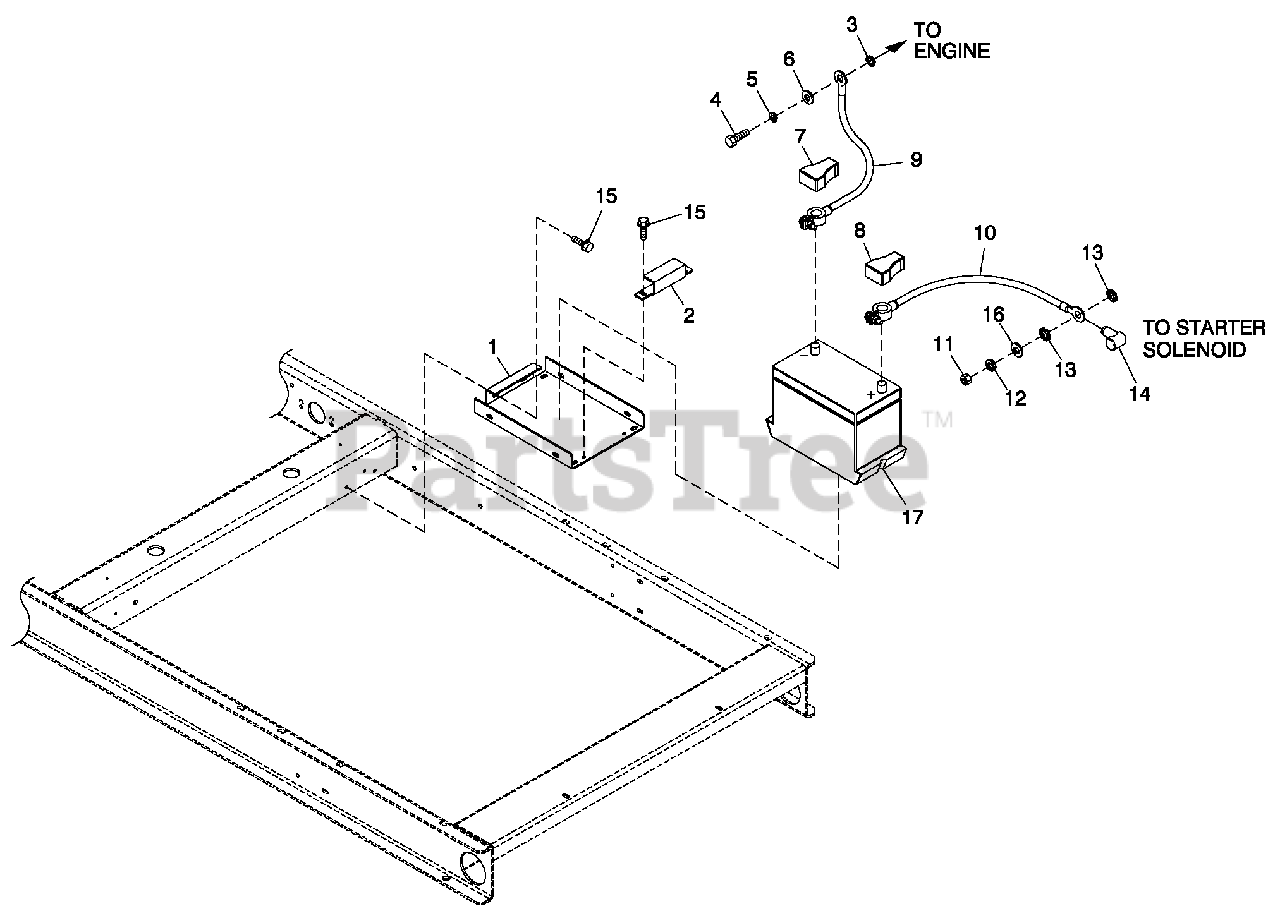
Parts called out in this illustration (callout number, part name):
1	BATTERY TRAY C1 CPL
2	STRAP BATTERY RETAINMENT
3	WASHER SHAKEPROOF EXT 7/16 STL
4	SCREW HHC M10-1.25 X 25 G8.8
5	WASHER LOCK M10
6	WASHER FLAT 3/8-M10 ZINC
7	BATTERY POST COVER RED +
8	BATTERY POST COVER BLACK -
9	CABLE BATTERY BLACK #1 X 18.00
10	CABLE BATT RED #1 X 18.00
11	NUT HEX M8-1.25 G8 YEL CHR
12	WASHER LOCK M8-5/16
14	BOOT CONTACTOR CABLES
15	SCREW THF M6-1 X 16 N WA Z/JS
16	WASHER FLAT 5/16-M8 ZINC
17	BATTERY 12VDC 75-AH 26
